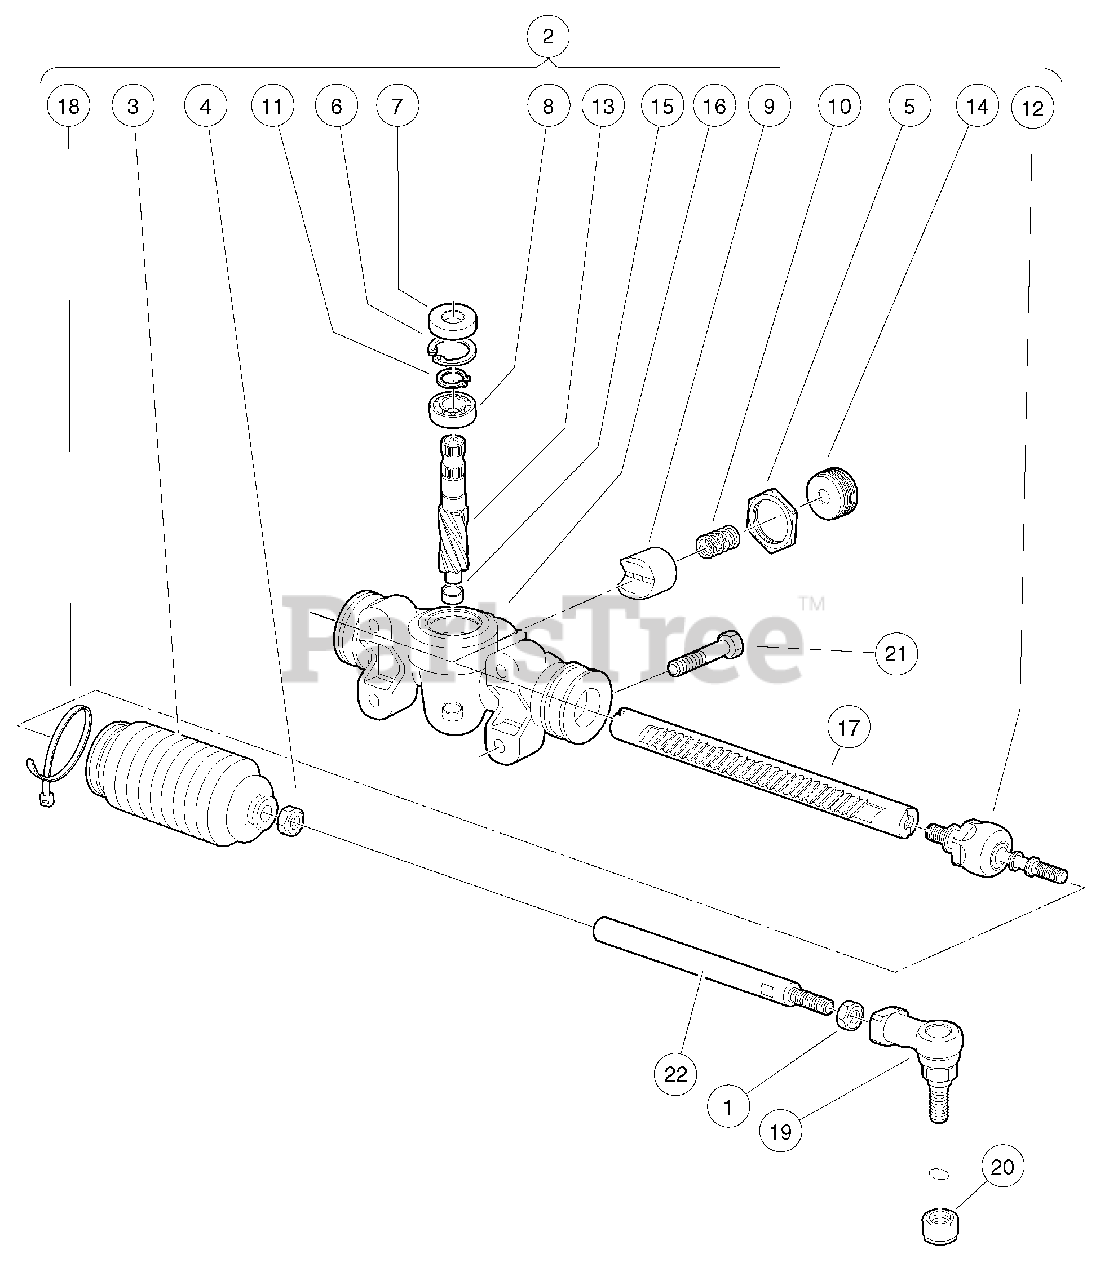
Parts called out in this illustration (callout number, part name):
1	Nut, 12mm Hex
2	Steering Rack
3	Bellows, Long
4	Nut, 12mm Hex
5	Rack Screw Locknut
6	Snap Ring
7	Seal, Steering Pinion Dust
8	Bearing, Ball
9	Support Yoke
10	Rack Guide Pressure Spring
11	Ring, Stop, C-Type
12	Inner Ball Joint Asm
13	Pinion, Steering
14	Bearing, Lower Pinion
15	Screw, Rack Guide
16	Housing, Steering Gear
17	Rack, Steering
18	Tie Wrap, 8" Nylon
19	End, Tie Rod M12 X 1.25
20	Locknut, M12-1.25 Nylon
21	Bolt, Flange Head, M10x 1.5 X 40 with Loctite
22	Link, Drag, Wt
